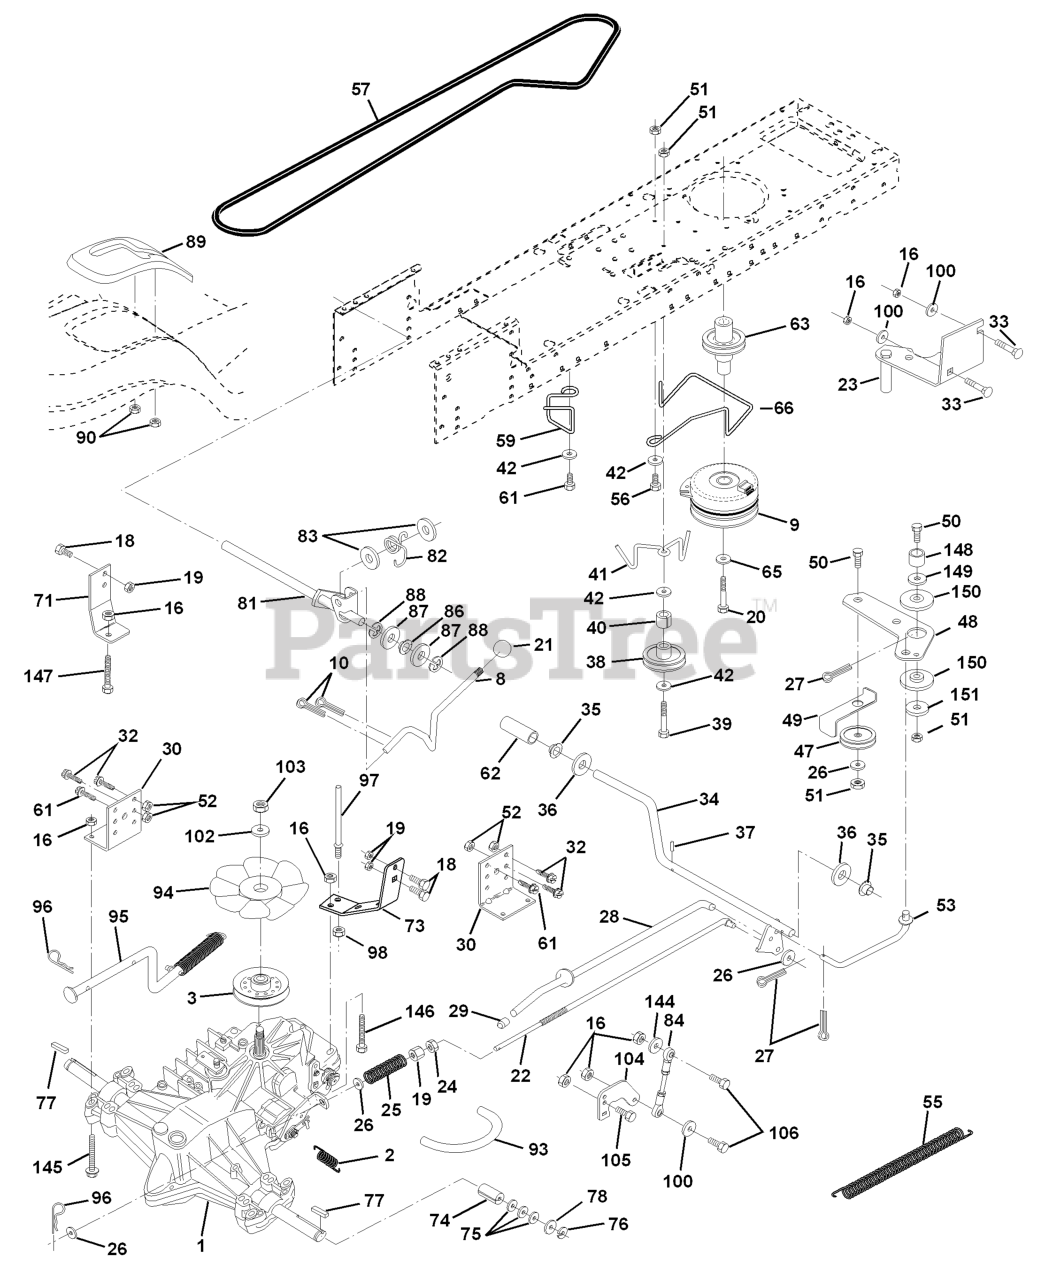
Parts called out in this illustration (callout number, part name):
1	TRANSAXLE ASSEMBLY
2	SPRING BRAKE
3	PULLEY, TRANSAXLE
8	ROD SHIFT FENDER
9	ELECTRIC CLUTCH
10	PIN COTTER
15	BOLT HEX 5/16-18 GR 5
16	NUT.71038.31-18.HEX.NYLOCK
18	BOLT
19	NUT
20	BOLT HEX
21	KNOB.DELUXE.(PISTOL.GRIP).BLAC
22	ROD BRAKE HYDRO
23	BRACKET, ASM CLUTCH MTG
24	NUT
25	SPRING ROD LT
26	WASHER
27	COTTER PIN
28	ROD BRAKE PARK LT
29	PLUNGER CAP
30	BRACKET TRANSAXLE
32	BOLT
33	RP BOLT 5/16-18 X3/4 ZN/YEL GR
34	SHAFT, FOOT PEDAL
35	BEARING.NYLON
36	WASHER LT
37	DRIVE PIN
38	PULLEY.IDLER.FLAT
41	KEEPER, BELT IDLER
42	WASHER
47	IDLER PULLEY
48	BELLCRANK, CLUTCH
49	RETAIN BELT
50	BOLT
52	LOCKNUT
53	LINK, CLUTCH LT
55	SPRING, RETURN LT
57	BELT.V.GROUND.DRIVE.HYDRO
59	KEEPER CENTER SPAN
61	SCREW
62	COVER, PEDAL (1 2)
63	ENGINE PULLEY
65	LOCKWASHER
66	BELT KEEPER
71	STRAP LH TORQUE
73	STRAP TORQUE RH HYDRO
74	SPACER SPLIT
77	SQUARE KEY
82	SPRING,TORSION
83	WASHER
89	SHIFT CONSOLE
90	NUT.PUSH.3/16
93	LINE FUEL HYD 4"
94	FAN 7" HYDRO
95	CONTROL ARM, BYPASS HYDRO
96	RETAINER M
97	KEEPER BELT RH
100	WASHER M
103	NUT.HEX.1/2-20
104	CONTROL ARM
106	BOLT.5/16-18X1-1/4 FULL.THREAD
144	Washer 11/32 x 5/8 x 16 Ga.
145	BOLT
146	Bolt Hex Flghd 5/16-18 x 2-1/4
147	Bolt Hex Flghd 5/16-18 x 1-1/2
149	SPACER RETAINER
150	BUSHING NYLON COLLERED
151	WASHER 12/32X2X10GA
